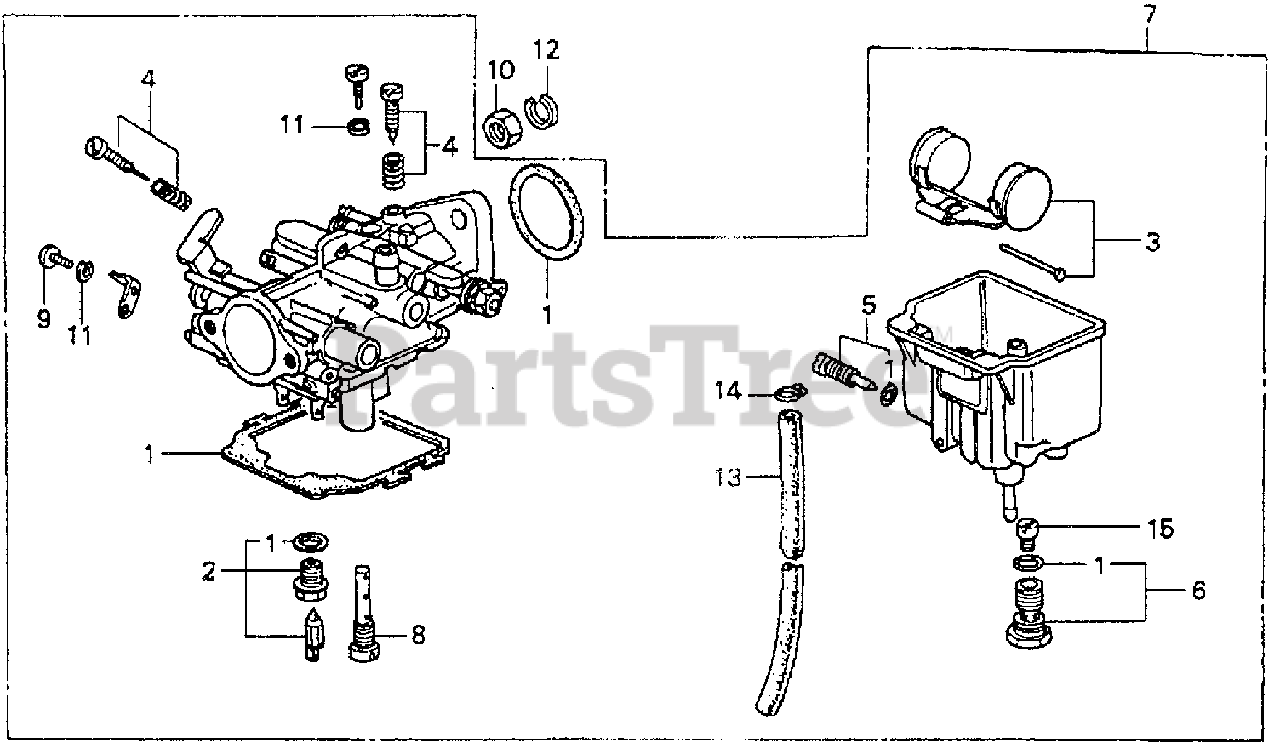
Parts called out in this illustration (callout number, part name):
1	GASKET SET
2	VALVE SET, FLOAT
4	SCREW SET A
5	SCREW SET, DRAIN (NOT AVAILABLE)
6	SCREW SET B (NOT AVAILABLE)
7	CARBURETOR ASSY. (NOT AVAILABLE)
8	NOZZLE, MAIN (NOT AVAILABLE)
9	SCREW, PAN (3X7) (NOT AVAILABLE)
10	NUT, HEX. (6MM)
11	WASHER, SPRING (3MM)
12	WASHER, SPRING (6MM)
13	BULK HOSE, FUEL (3.5X3000) (3.5X150)
14	CLIP, TUBE (B7)
15	JET, MAIN (#90) (NOT AVAILABLE)
